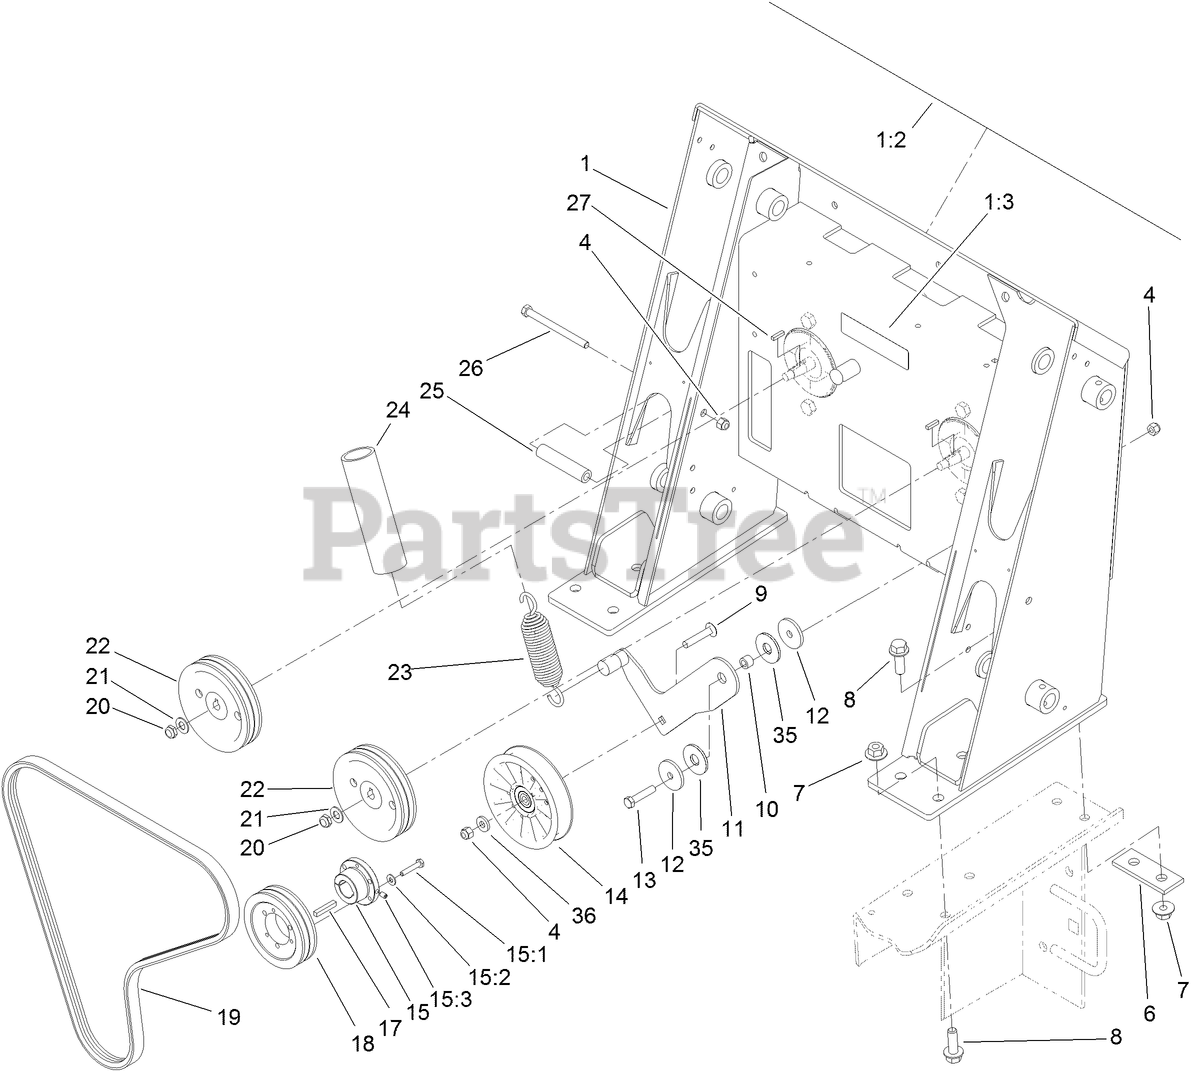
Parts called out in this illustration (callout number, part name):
1	LOADER TOWER ASM
1:2	DECAL-PANEL, CONTROL
1:3	DECAL-DANGER
4	NUT-HF, NI
6	PLATE-STIFFENER
7	NUT-LOCK, FLANGE
8	SCREW-HHF
9	BOLT-CARRIAGE
10	SPACER
11	ARM-IDLER
12	WASHER-PLAIN
13	SCREW-HH
14	PULLEY-IDLER
15	BUSHING
15:1	SCREW-HH
15:2	WASHER-LOCK
15:3	SCREW-SET, HSH
17	KEY-SQUARE
18	PULLEY
19	V-BELT
20	NUT-LOCK, NI
21	WASHER-FLAT
22	PULLEY-3V
23	SPRING-EXTENSION
24	RETAINER-SPRING
25	TUBE-SPACER
26	SCREW-HH
35	WASHER-FRICTION, COMPOSITE
36	SPACER
